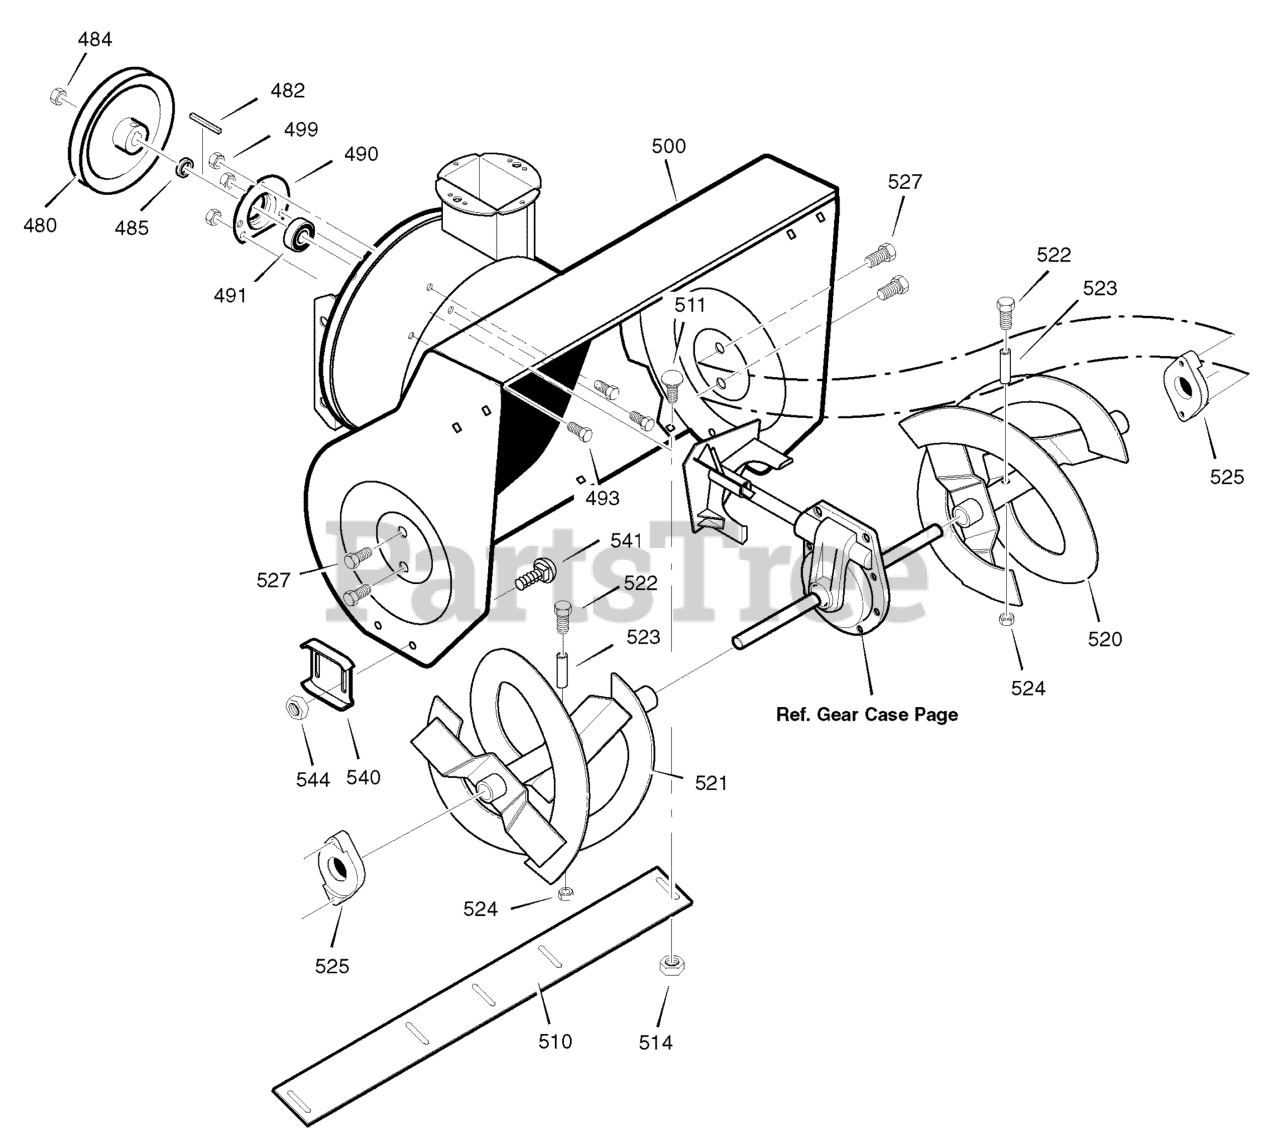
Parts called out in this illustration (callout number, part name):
480	PULLEY, 4L 8.40 OD
482	KEY, SQUARE 3/16 X 3/4
484	NUT, 1/2-20
485	SPACER, FRICTION PULLEY
490	RETAINER, BALL BRNG
491	BEARING, BALL
493	BOLT, HEX 5/16-18X .50
499	NUT, 5/16-18 HEXWDFLLK
500	HOUSING, ASSY
510	BLADE, SCRAPER
511	BOLT, 5/16-18X.75
514	NUT, 5/16-18
520	AUGER, ASSY, LH
521	AUGER, ASSY, RH
522	SCREW, 1/4-20 X 1.75
523	SPACER, SLEEVE
524	NUT, 1/4-20
525	BEARING, FLANGE
527	SCREW, 5/16-18 X .75
540	SKID, HEIGHT ADJUST
541	BOLT, 5/16-18 X .75
544	NUT, 5/16-18
